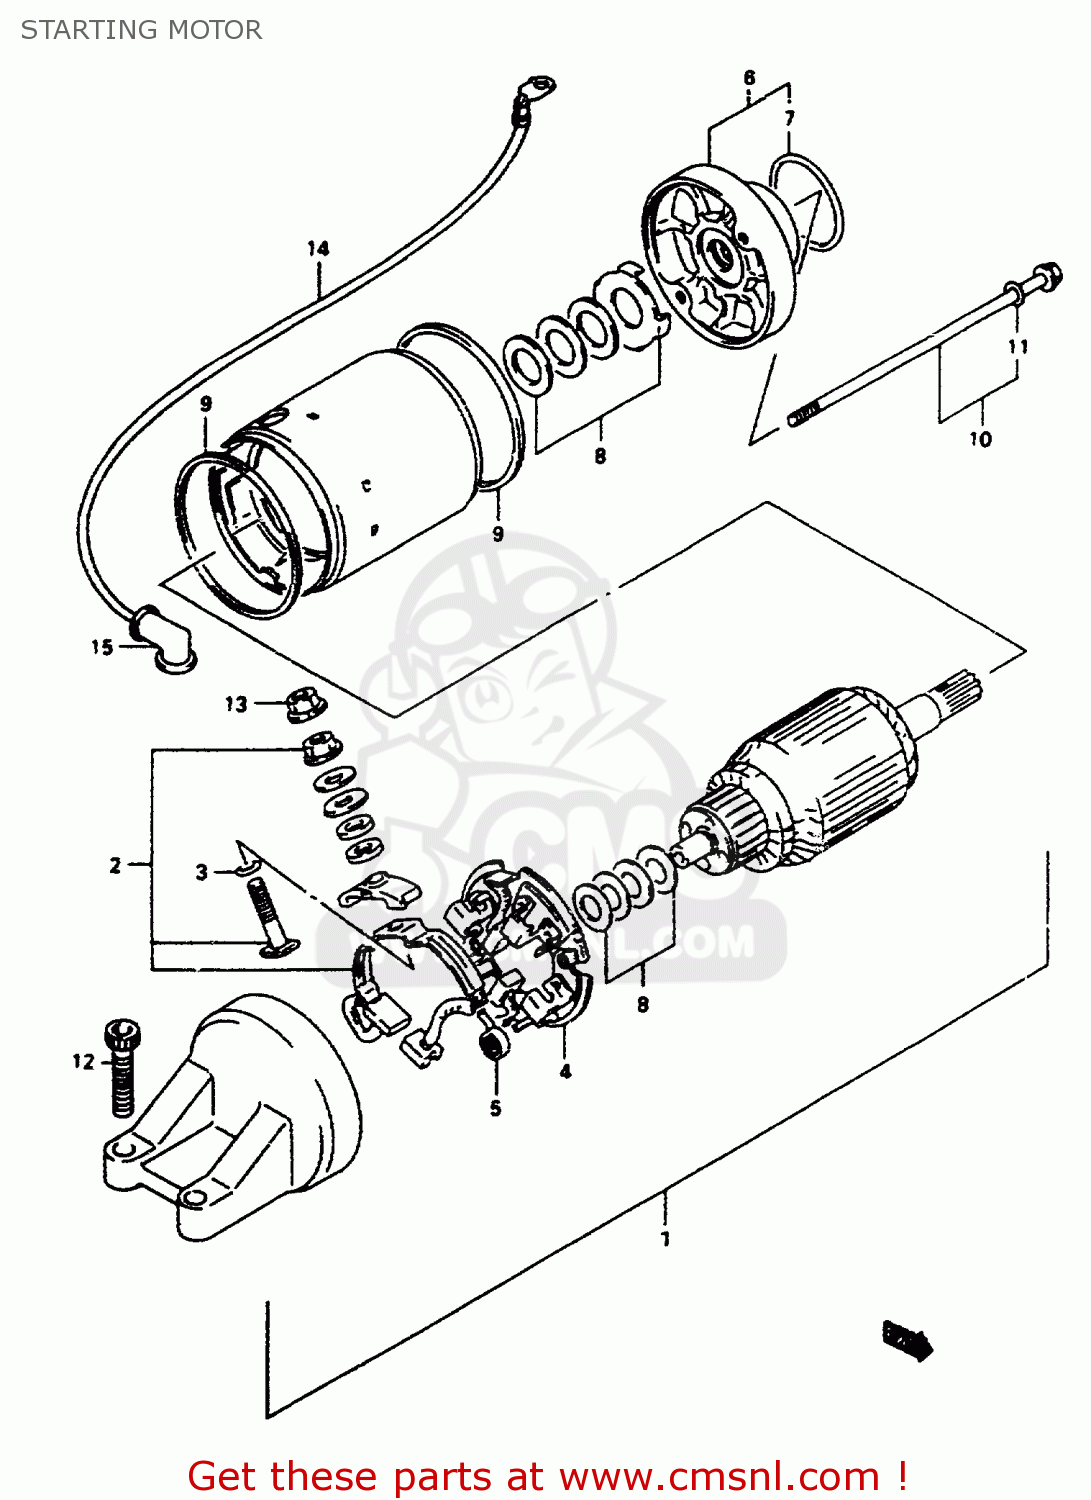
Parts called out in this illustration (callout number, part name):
1	MOTOR ASSEMBLY,STARTING
2	TERMINAL SET,BRUSH,PLUS
3	O RING
4	BRUSH,HOLDER SET
5	SPRING,BRUSH
6	BRACKET ASSEMBLY,FRONT
7	O RING
8	SHIM SET,STARTING MOTOR
9	O RING
10	BOLT SET,STARTING MOTOR
11	O RING
12	BOLT
13	NUT
14	WIRE,STARTER MOTOR LEAD
15	CAP,STARTER MOTOR LEAD
